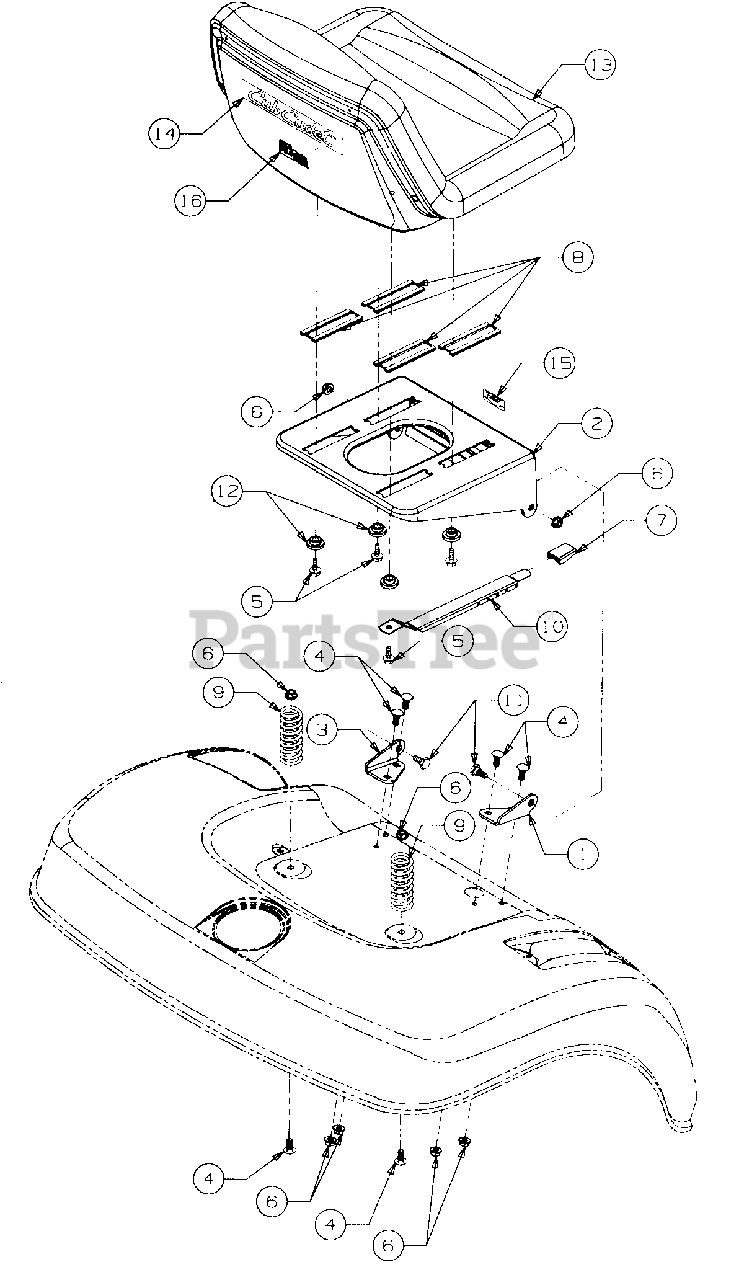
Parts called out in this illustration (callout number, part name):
5	Screw, Hex Wash Sf-Tapp 5/16-18 X.75 Lg
6	Nut, Hex Flange Top Lock 5/16-18
7	Knob, Seat Adjuster
8	Slide, Seat
9	Spring, Compression 1.9 OD x 2.4 Lg
10	Adjuster, Seat
11	Bolt, Shoulder
12	Spacer, Shoulder
13	Seat, Medium Back
14	Graphic, Seat Back Script
15	Graphic, Seat Adjuster
16	Graphic, Made in USA
